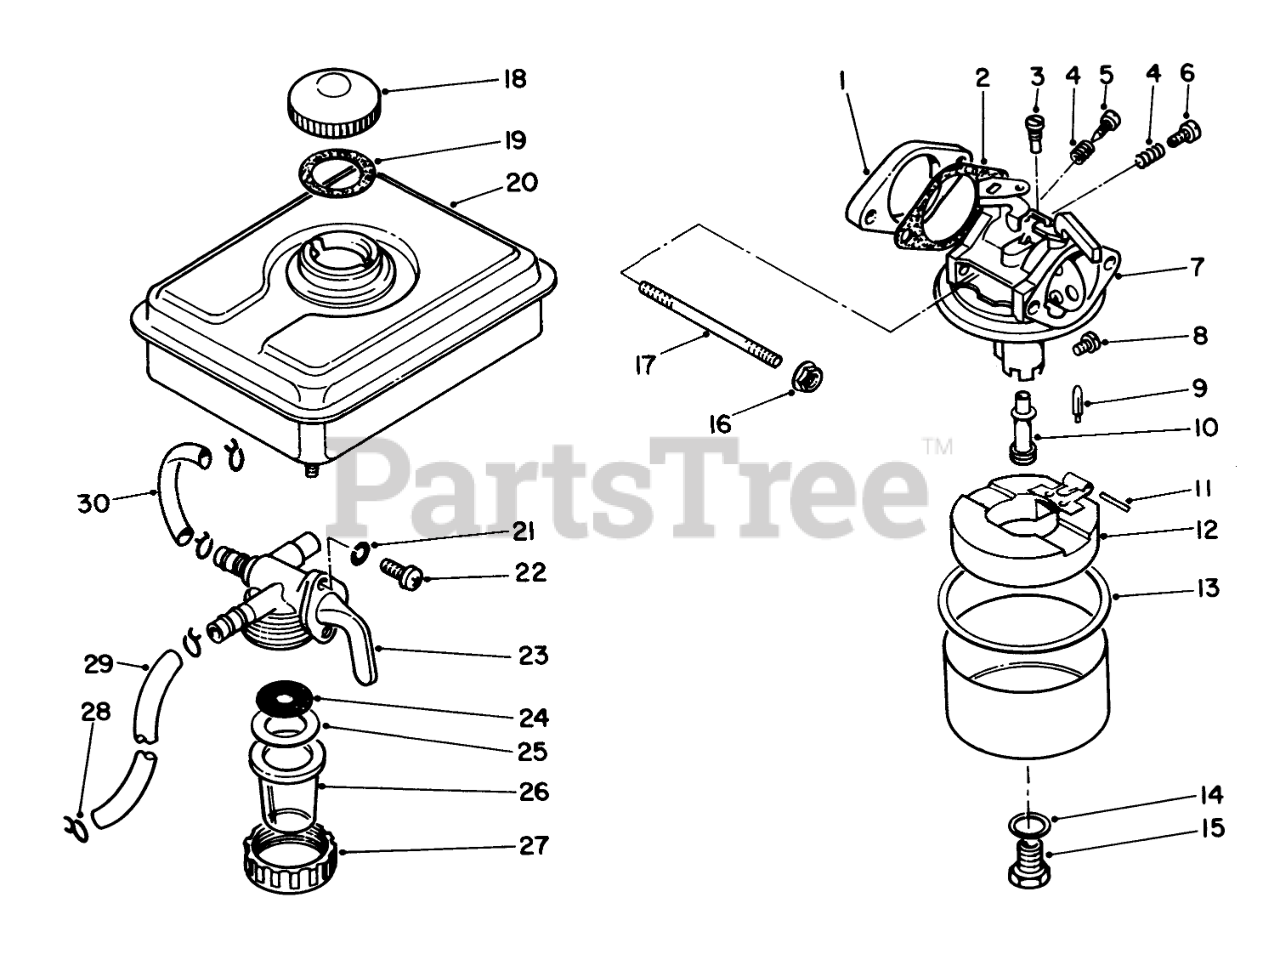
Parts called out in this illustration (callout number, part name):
1	INSULATOR
2	GASKET
3	PILOT JET
4	SPRING
5	ADJUSTER
6	SCREW
7	Carburetor Assembly (Incl. Ref. #8-15)
8	MAIN JET
9	NEEDLE VALVE
10	NOZZLE
11	Pin
12	Float
13	GASKET
14	GASKET
15	Bolt
17	Stud Bolt
19	GASKET
20	Tank-Fuel
21	Lockwasher
22	Screw
23	Petcock Assembly (Incl. Ref. #24-27)
24	FILTER
25	GASKET
